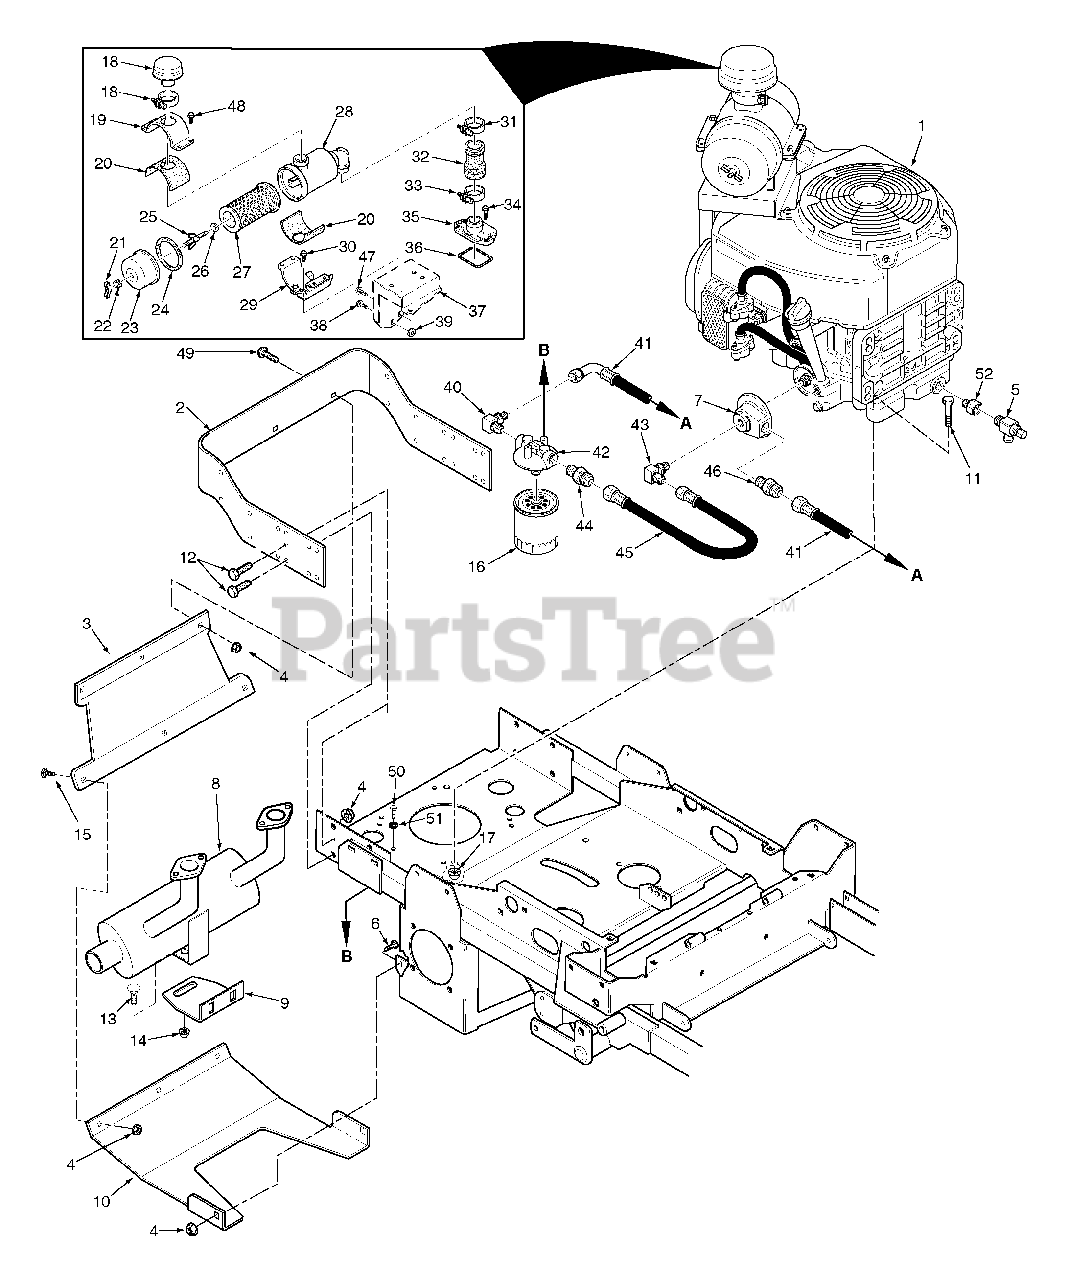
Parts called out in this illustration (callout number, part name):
1	Engine, Honda 24 HP (GXV670TAF2)
2	Bumper, Rear
3	Shield, Rear
4	Nut, Serr. Flange 3/8-16
5	Extension, Oil Drain 2.3"
6	Bolt, Carr. 3/8-16 x 1"
7	Adapter, Oil Filter
8	Muffler, Honda
9	Bracket, Muffler
10	Plate, Skid
11	Bolt, Hex Head 5/16-18 x 1-1/2"
12	Bolt, Hex Head 3/8-16 x 1"
13	Bolt, Hex Head 5/16-18 x 3/4"
14	Nut, Serr. Flange 5/16-18
15	Bolt, Carr. 3/8-16 x 3/4"
16	Oil Filter
17	Nut, Serr. Flange 5/16-18
18	Pre-Cleaner, Engine Air
19	Holder, Air Cleaner Upper
20	Rubber, Air Cleaner Holder
21	Wing Nut - 16mm
22	Grommet, Air Cleaner
23	Cover, Air Cleaner
24	Seal, Air Cleaner
25	Bolt, Air Cleaner
26	Washer, Air Cleaner
27	Element, Air Cleaner
28	Housing, Air Cleaner
29	Holder, Air Cleaner Lower
30	Bolt, Flange (6mm x 16)
31	Band, Air Cleaner Connecting Tube
32	Tube, Air Cleaner Connecting
33	Band, Air Cleaner Connecting Tube
34	Bolt, Flange (6mm x 28)
35	Joint B, Connecting Tube
36	Seal, Air Cleaner Housing
37	Stay, Engine Air Cleaner
38	Bolt, Flange (6mm x 14)
39	Collar, Seat
40	Elbow, 90 Degree 3/8 - 3/8
41	Hose, Remote Oil Filter Inlet
42	Filter Head
43	Elbow, 90 Degree 3/8 - 3/8
44	Tube, Union 1/2 - 3/8
45	Hose, Remote Oil Filter Return
46	Tube, Union 1/2 - 3/8
47	Bolt, Flange (8mm x 16)
48	Bolt, Flange (6mm x 12)
49	Bolt, 3/8-16 x 1" Torx
50	Bolt, Hex Head 1/4-20 x 5/8"
51	Lockwasher, 1/4" Spring
52	Adapter, M20 x 1.5 / 3/8-18
